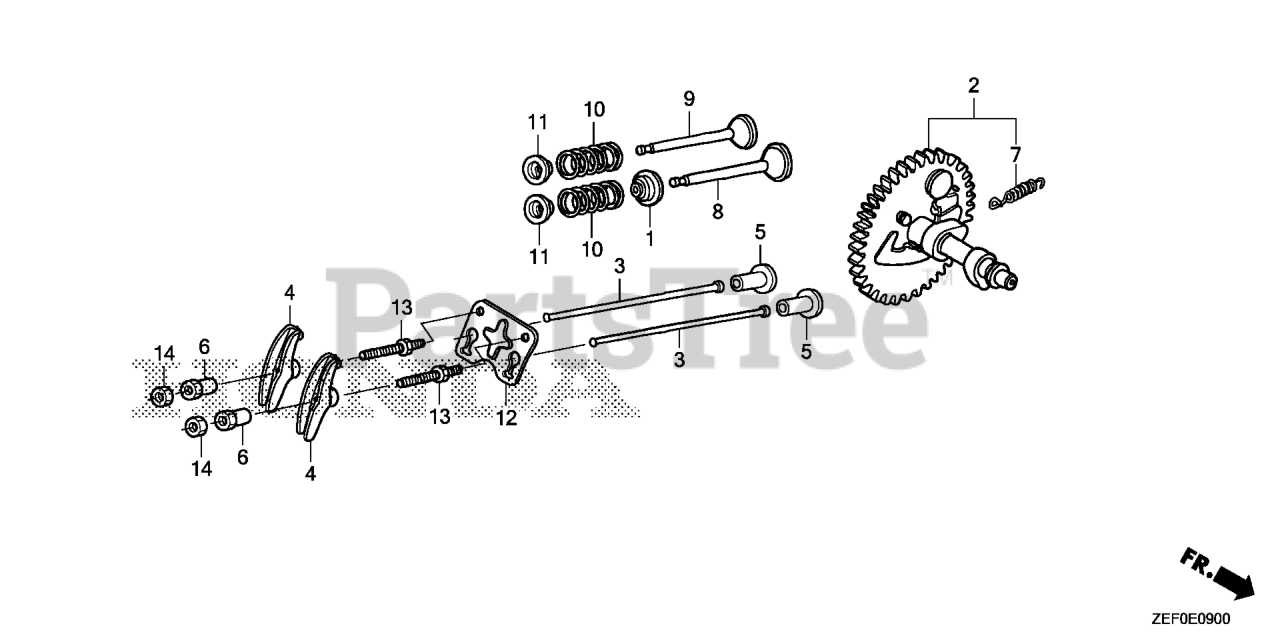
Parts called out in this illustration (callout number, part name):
1	SEAL, VALVE STEM
2	CAMSHAFT ASSY.
3	ROD, PUSH
4	ARM, VALVE ROCKER
5	LIFTER, VALVE
6	PIVOT, ROCKER ARM
7	SPRING, WEIGHT RETURN
8	VALVE, IN.
9	VALVE, EX.
10	SPRING, VALVE
11	RETAINER, VALVE SPRING (EXHAUST SIDE)
12	PLATE, PUSH ROD GUIDE
13	BOLT, PIVOT (8MM)
14	NUT, PIVOT ADJ.
